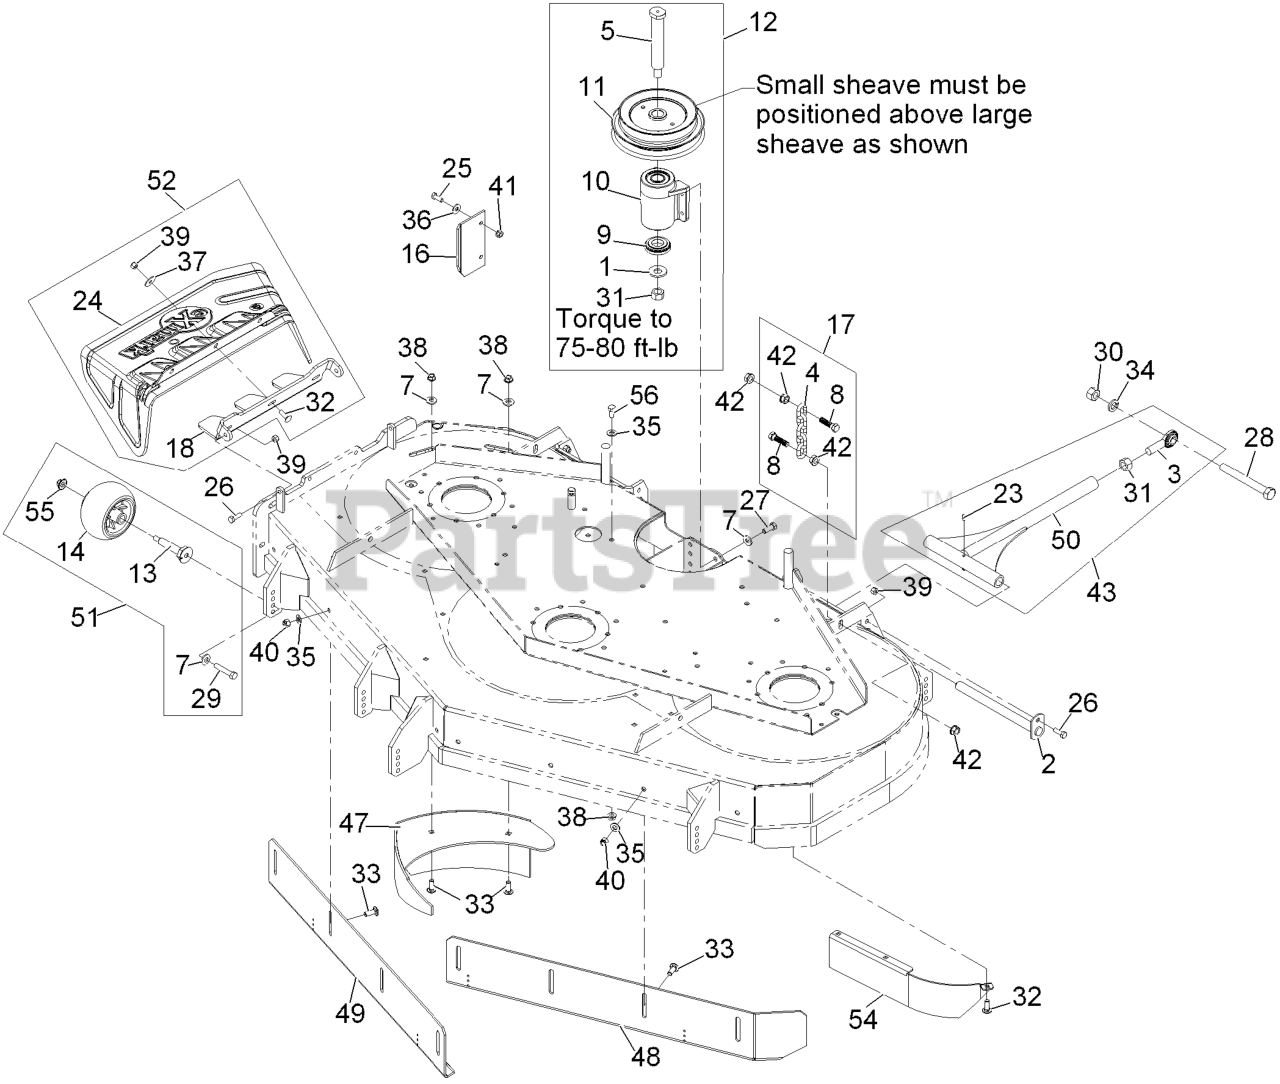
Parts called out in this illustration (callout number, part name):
1	WASHER-SPRING
2	PIN-STRUT
3	BALLJOINT-SPHERICAL
4	CHAIN-LIFT, DECK
5	JACKSHAFT
7	WASHER-BELLEVILLE
8	SCREW-HH
9	SPACER-GUARD, BOTTOM
10	KIT, JACKSHAFT ASSY
11	SHEAVE, JACKSHAFT DOUBLE
12	KIT,JACKSHAFT 60/72-3750
14	ROLLER-SCALP, ANTI
16	DEFLECTOR,DISCHARGE
17	DECK CHAIN ASM
18	HINGE,DISCHARGE CHUTE
24	CHUTE,DISCHARGE LZ
25	SCREW-HH
26	SCREW-HH
27	SCREW-HH
28	SCREW-HH
29	SCREW-HH
30	NUT-HEX
31	NUT-HEX
32	SCREW-CARR
33	SCREW-CARR
34	WASHER-LOCK
35	WASHER-FLAT
36	WASHER-FLAT
37	WASHER-FLAT
38	NUT-HHF, WHIZ
39	NUT-LOCK, NI
40	NUT-LOCK, NI
43	ASM,DECK STRUT XS 72
47	WLD,DOGLEG 725
48	WLD,BAFFLE FRT ADJ LH 725
49	WLD,BAFFLE FRT ADJ RH 725
50	WLD,DECK STRUT
52	ASM, DISCHARGE CHUTE
54	BAFFLE,SCROLL 725
55	Nut-Nyloc 3/8-16 Flg
56	SCREW-HH
